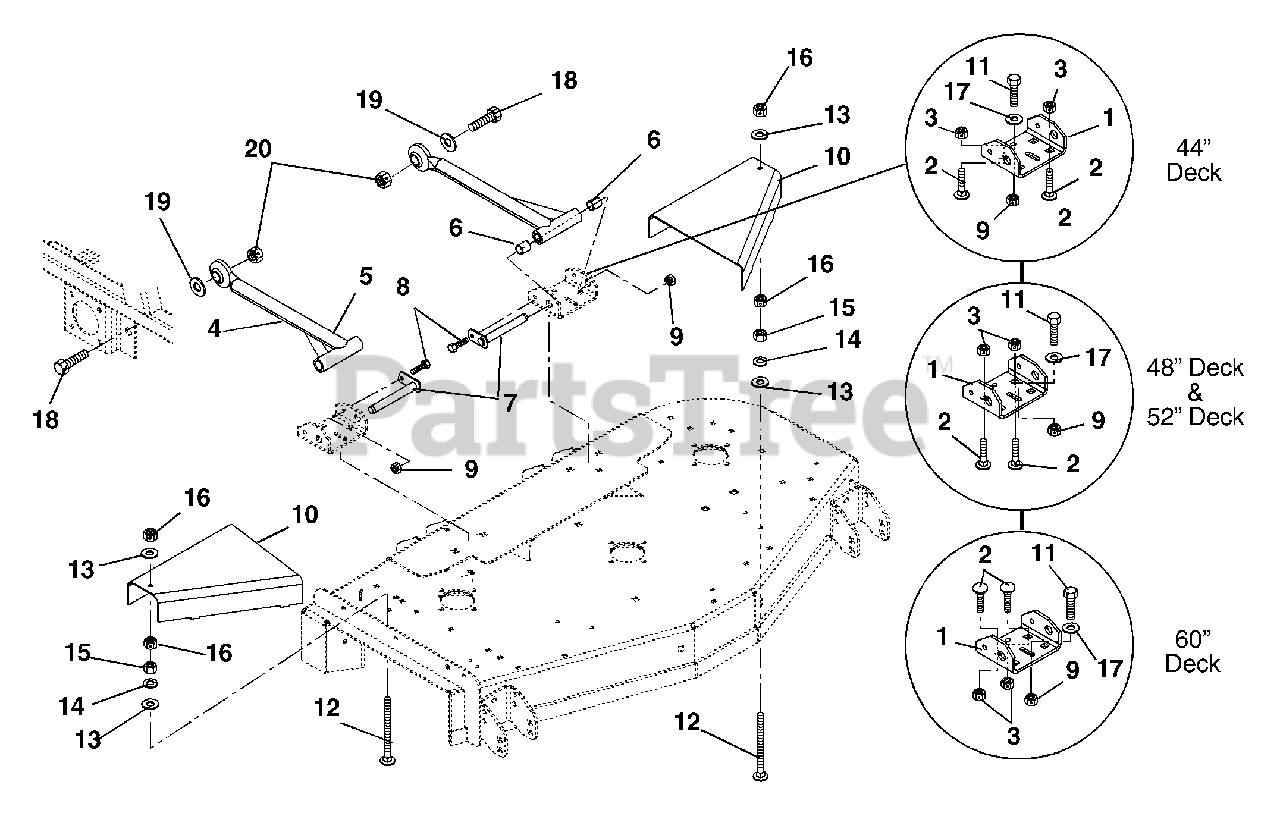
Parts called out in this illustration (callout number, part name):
1	Bracket, Mower Mounting (Rear)
2	Bolt-Round Head Square Neck .50-13 x 1.00 Grade 5
3	Nut, Locking Center Jam .50-13
4	Assembly, Mower Mounting
5	Mower Mounting Arm
6	Bearing .75 x .875 x 1.00
7	Weldment, Mower Mounting Pin
8	Bolt-Hex .38-16 x .75 Grade 5
9	Nut-Locking-Top-Flange .38-16
10	Guard, Pulley (042, 043)
10	Guard, Pulley Right Hand (044)
10	Guard, Pulley Left Hand (044)
10	Guard, Pulley Left Hand (051)
10	Guard, Pulley Right Hand (051)
11	Bolt-Hex .38-16 x 1.00 Grade 5
12	Bolt-Round Head Square Neck .31-18 x 3.50 Grade 5 (042, 043, 044, 310, 311)
12	Bolt-Round Head Square Neck .31-18 x 3.50 Grade 5 (051)
13	Washer-Flat-Steel .344 x .688 x .065 (042, 043, 044, 310, 311)
13	Washer-Flat-Steel .344 x .688 x .065 (051)
14	Washer-Locking .31 x .078 (042, 043, 044, 310, 311)
14	Washer-Locking .31 x .078 (051)
15	Nut-Hex .31-18 (042, 043, 044, 310, 311)
15	Nut-Hex .31-18 (051)
16	Nut-Locking-Center .31-18 (042, 043, 044, 310, 311)
16	Nut-Locking-Center .31-18 (051)
17	Washer-Flat-Steel .406 x .812 x .065
18	Bolt-Hex .875-9 x 2.75 Grade 5
19	Washer-Flat-Steel .875 x 1.50 x .120
20	Nut-Locking-Center .875-9
